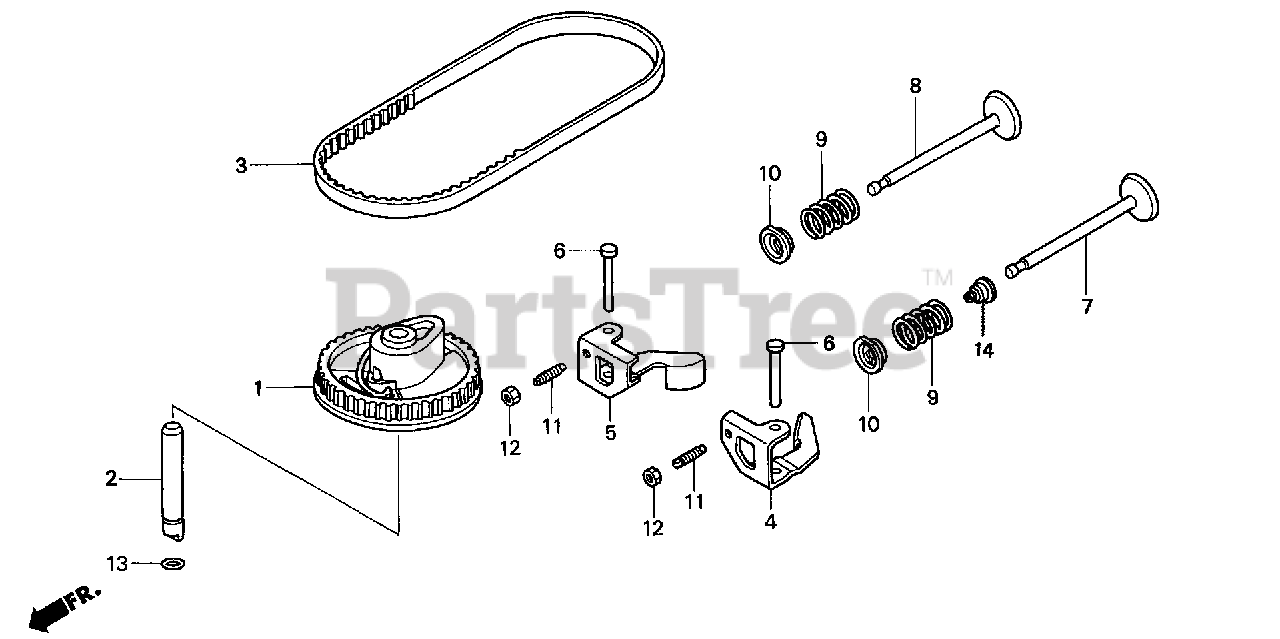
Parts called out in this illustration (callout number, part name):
1	PULLEY, CAMSHAFT
2	SHAFT, CAM PULLEY
3	BELT, TIMING (84HU7 G-200)
4	ARM, IN. VALVE ROCKER
5	ARM, EX. VALVE ROCKER
6	SHAFT, ROCKER ARM
7	VALVE, IN. (TECHNOSTAR)
7	VALVE, IN. (ROCKNEL)
8	VALVE, EX.
9	SPRING, VALVE
10	RETAINER, IN. VALVE SPRING
11	SCREW, TAPPET ADJUSTING
12	NUT, TAPPET ADJUSTING
13	O-RING (6.8X1.9) (ARAI)
14	SEAL, VALVE STEM
